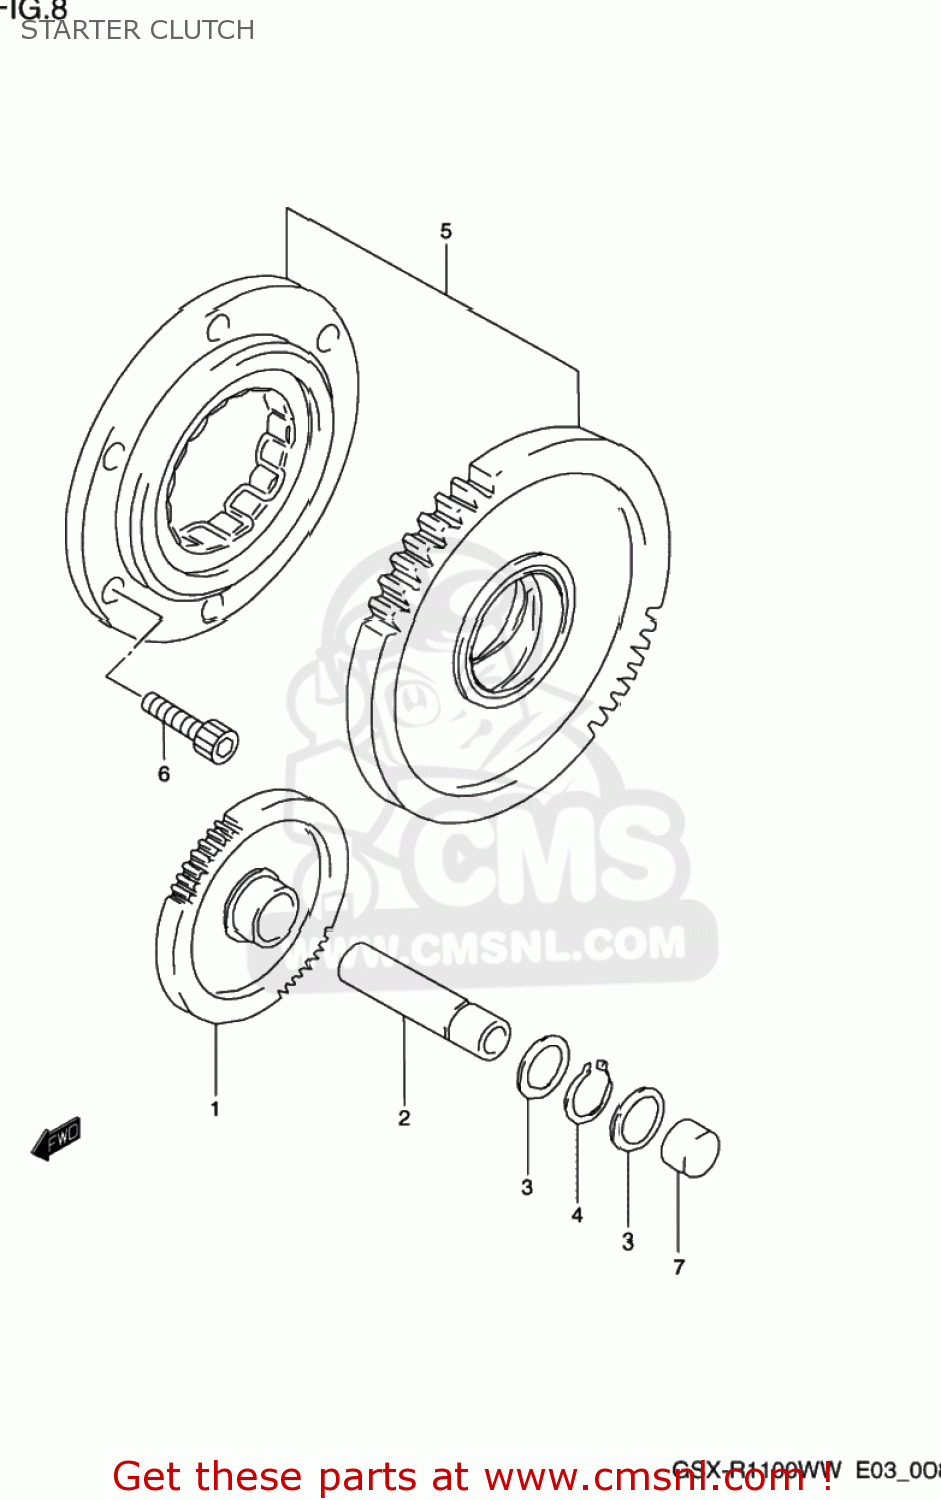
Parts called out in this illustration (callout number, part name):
1	GEAR,STARTER IDLE
2	SHAFT,STARTER IDLE GEAR
3	WASHER
4	CIRCLIP,12 MM
5	CLUTCH SET,STARTER
6	BOLT
7	PLUG
